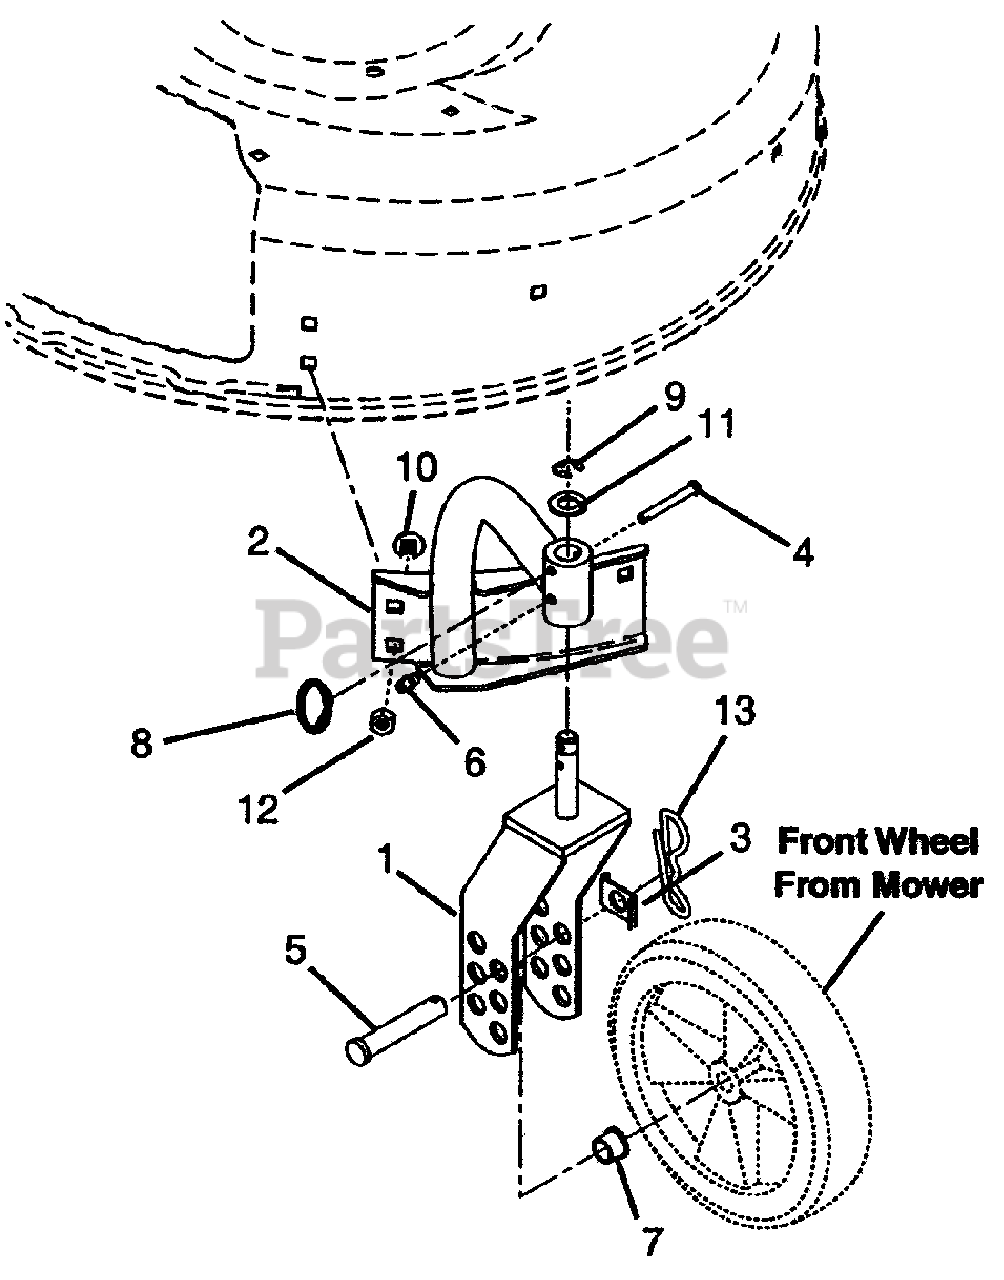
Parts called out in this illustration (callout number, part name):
1	WHEEL YOKE WELDMENT
2	MOUNT W/BUSHING, LEFT ARM
3	AXLE TAB
4	PIN-CLEV .25X1.75 YWZC
5	PIN-CLEV .494X2.62 YWZC
6	FTG-LUBE .25-28X.256 YWZC
7	BSHG-FLG .500X.625X.500X.750
8	KICKOUT RING YWZC
9	RG-RTNG-EXT .625X.042
10	@BLT-RDHDSQNK .31-18X.50 G5YZ
11	WSHR-FL-STL .630X1.005X.062 YZ
12	@NUT-LK-CTR .31-18 YWZC
13	PIN, BOWTIE COTTER
